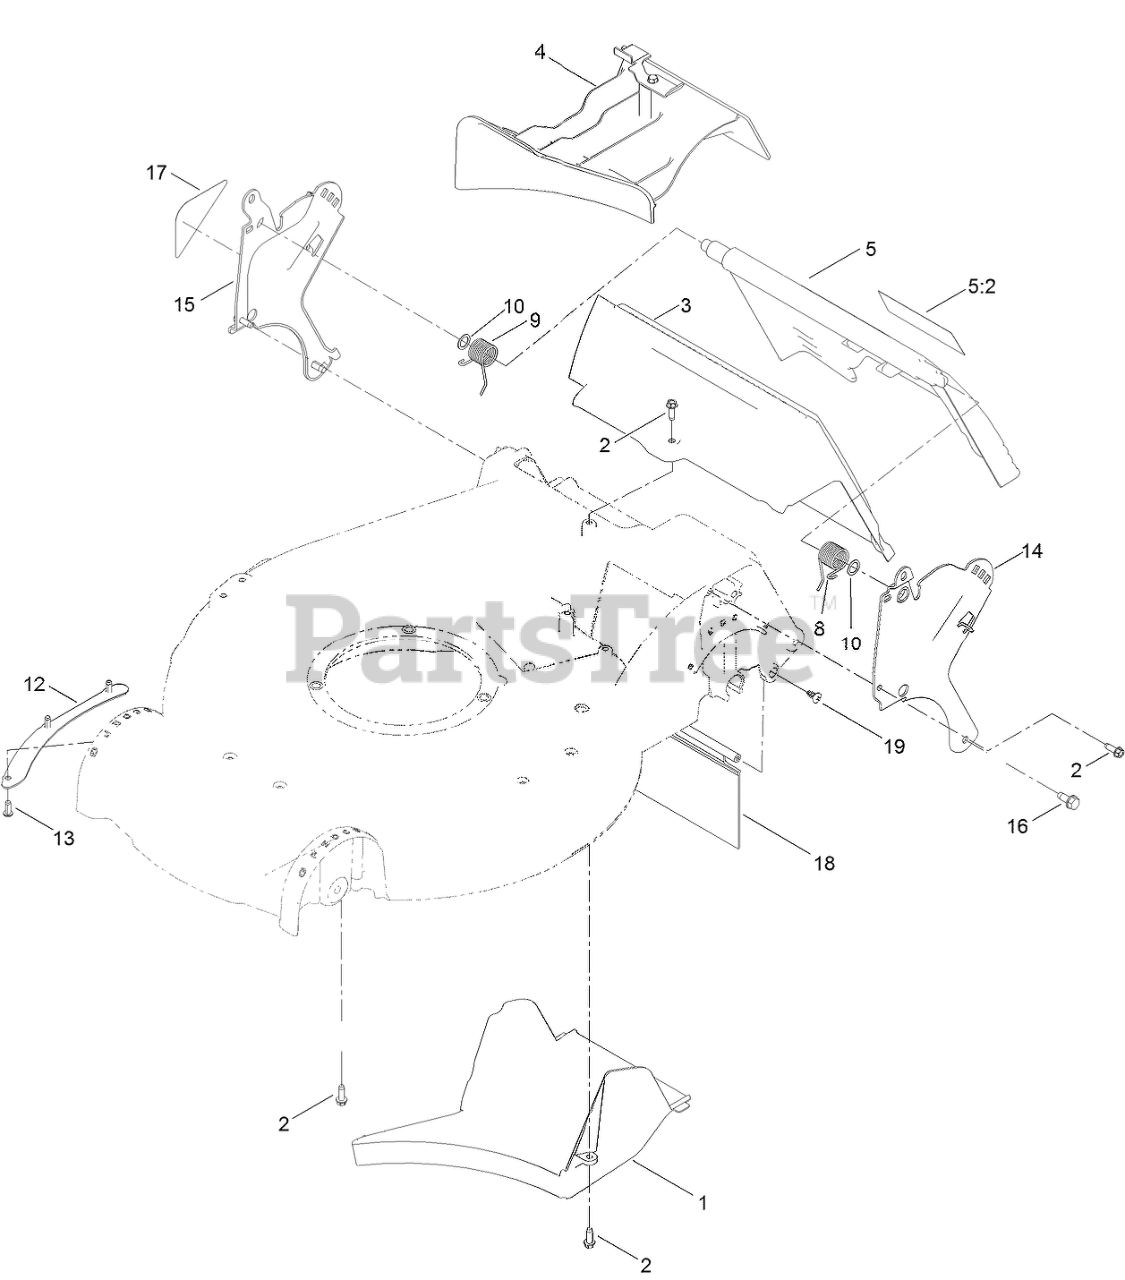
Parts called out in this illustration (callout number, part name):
1	TUNNEL-DISCHARGE
2	SCREW-HWHTF
4	MULCH PLUG ASM
5	REAR DOOR ASM
5:2	DECAL-WARNING
8	SPRING-TORSION
9	SPRING-TORSION
10	WASHER-NYLON
12	SHEET-LIP
13	SCREW
14	BRACKET-HANDLE, LH
15	BRACKET-HANDLE, RH
16	SCREW-THD ROLL, HWH
17	DECAL-INSTRUCTION
18	SHIELD-TRAILING
19	SCREW-PTH
